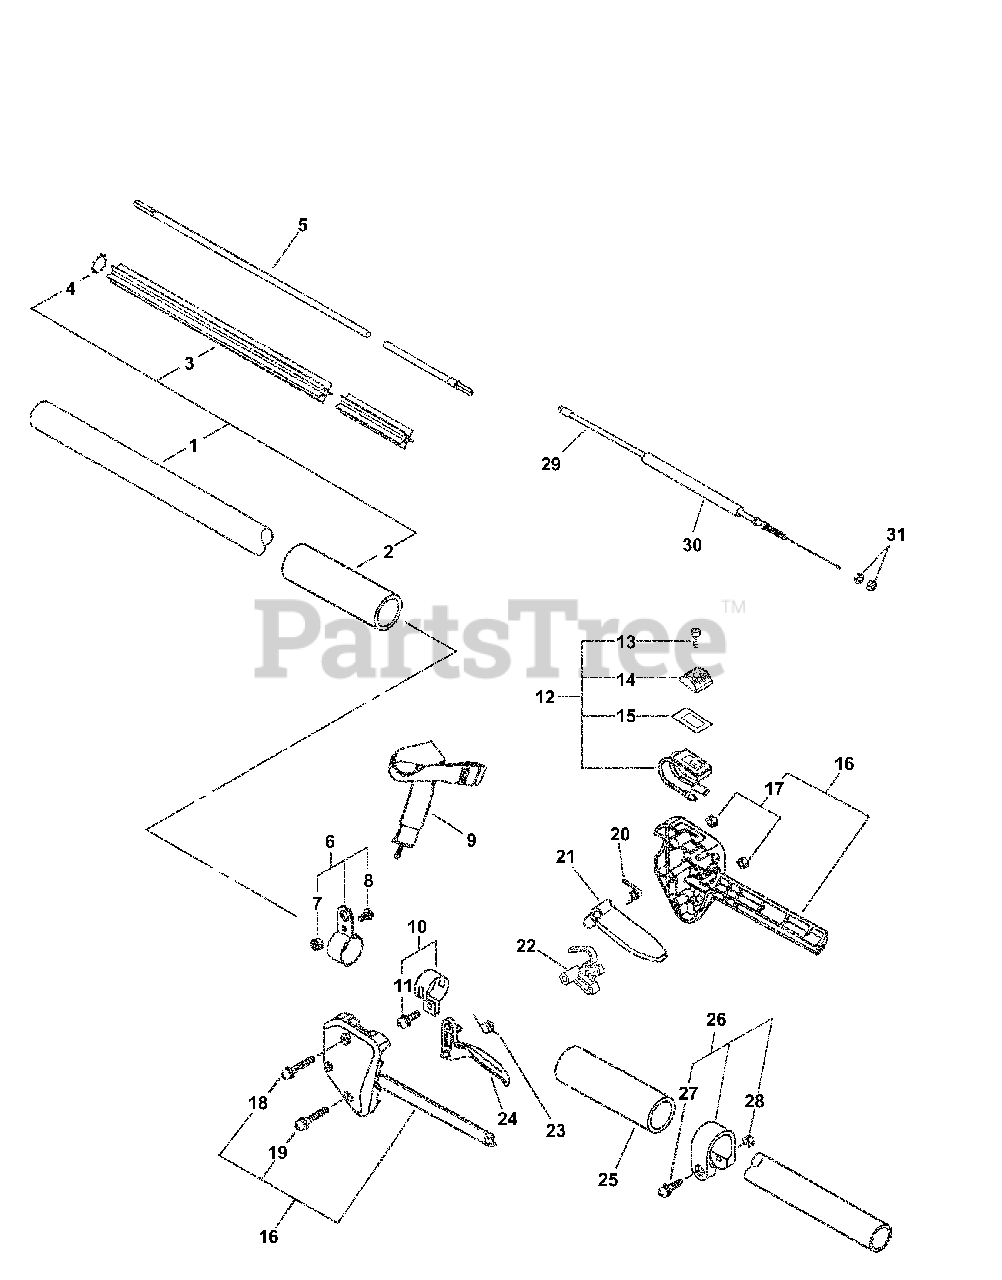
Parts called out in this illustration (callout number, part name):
1	PIPE, MAIN
2	GRIP, HANDLE
3	LINER - FLEXIBLE
5	DRIVESHAFT - FLEXIBLE
6	HANGER KIT
7	NUT, LOCK 10-24 UNC
8	SCREW
9	STRAP ASSY, SHOULDER
10	CLAMP KIT
11	SCREW 5×14
12	SWITCH ASSY, ON-OFF
13	SCREW 3×10
14	KNOB, SWITCH - ORANGE
15	LABEL, SWITCH
16	HANDLE KIT, CONTROL
17	NUT M5
18	SCREW 5×35
19	SCREW 5×25
20	SPRING, TORSION
21	LEVER, THROTTLE LOCKOUT
22	LOCKOUT, THROTTLE
23	SPRING, TORSION
24	TRIGGER, THROTTLE
25	GRIP, HANDLE
26	CLAMP KIT
27	SCREW 5×28
28	NUT M5
29	CABLE, THROTTLE
